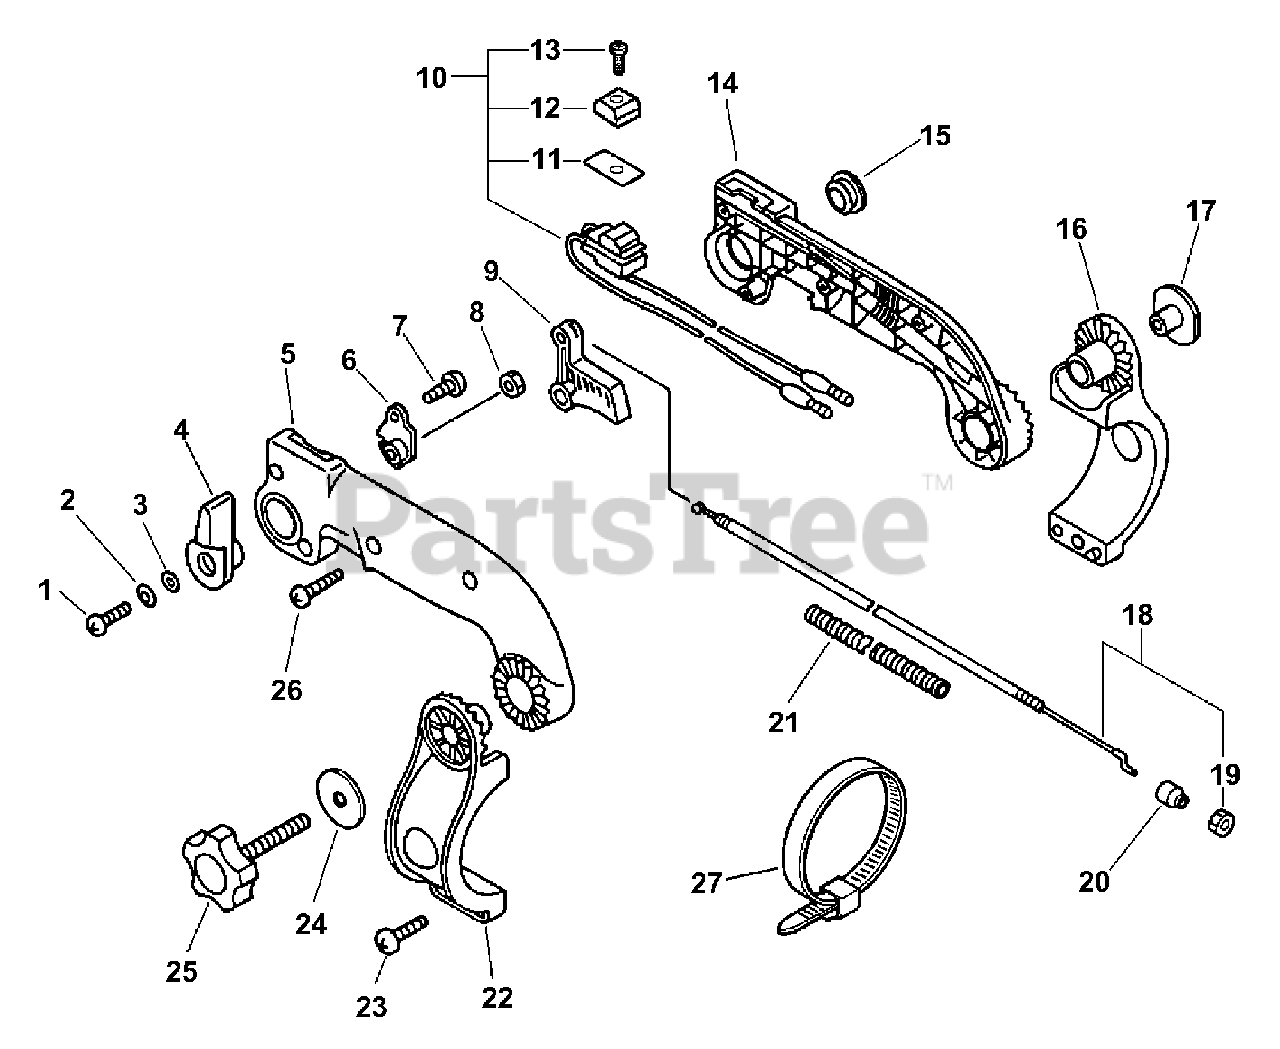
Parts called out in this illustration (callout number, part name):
1	SCREW - 6X20
2	LOCKWASHER - 6
3	WASHER - 6
4	CONTROL, THROTTLE
5	HANDLE, CONTROL - LEFT
6	BRACKET, THROTTLE
7	SCREW - 4X10
8	LOCKNUT - 6
9	TRIGGER, THROTTLE
10	IGNITION SWITCH ASSY
11	COVER, SWITCH - STOP
12	KNOB, SWITCH - ORANGE
13	SCREW - 3X10
14	HANDLE, CONTROL - RIGHT
16	BRACKET, HANDLE - RIGHT
18	CABLE, THROTTLE
19	LOCKNUT - 6
20	CAP, DUST
21	TUBE, PROTECTIVE - CORRUGATED
22	BRACKET, HANDLE - LEFT
23	SCREW - 5X20 -- TAPPING
24	WASHER - 6
25	THUMBSCREW
26	SCREW - 4X22
27	TIE, CABLE - LARGE
